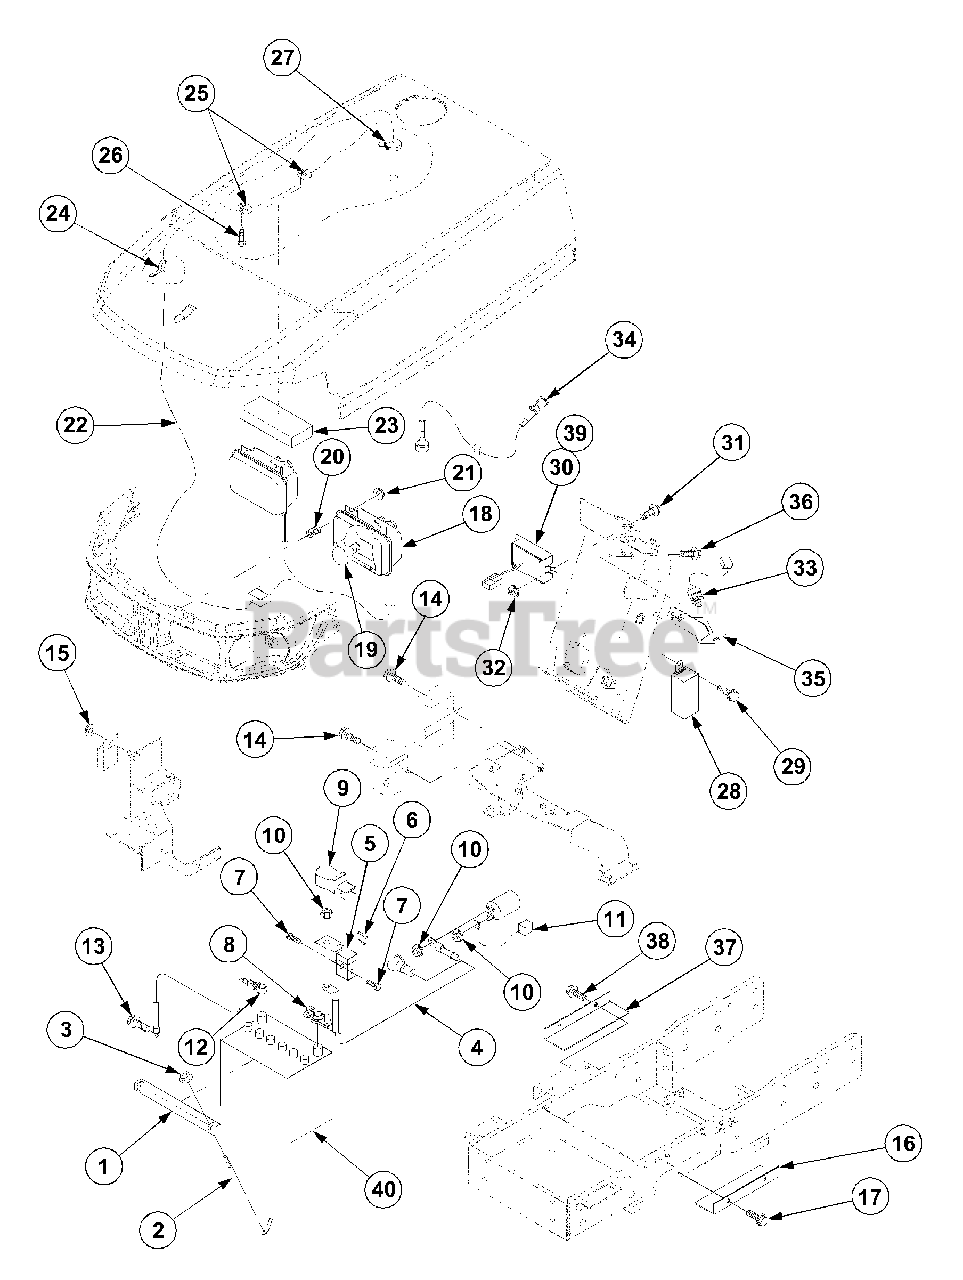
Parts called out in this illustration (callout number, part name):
1	Battery Clamp
5	Fuse Box
14	Bolt,w/Washer
17	Bolt,w/Washer
18	Front Lamp Assy
26	Screw,Tapping
29	Bolt,w/Washer
30	Relay Assy
33	Switch
34	Cable,Flexible
35	Plate,S.W.
36	Bolt,w/Washer
37	Cover
38	Bolt,w/Washer
40	Battery
